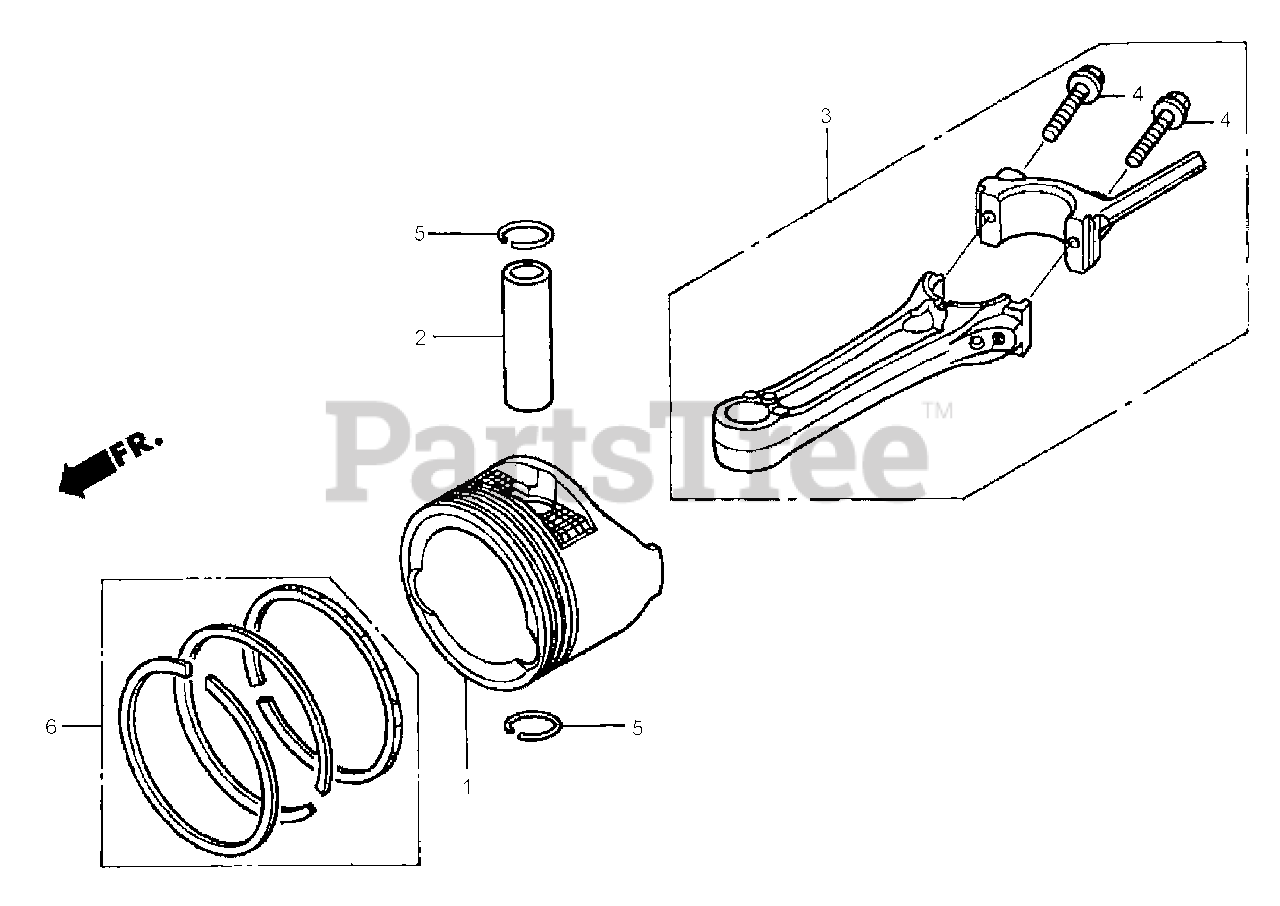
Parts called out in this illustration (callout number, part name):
1	PISTON
2	PIN-PISTON
3	CONNECTING ROD ASM
4	BOLT-ROD, CONNECTING
5	CLIP-PIN, PISTON (13MM)
6	RING SET-PISTON (RIKEN)
6	RING SET-PISTON (TEIKOKU)
